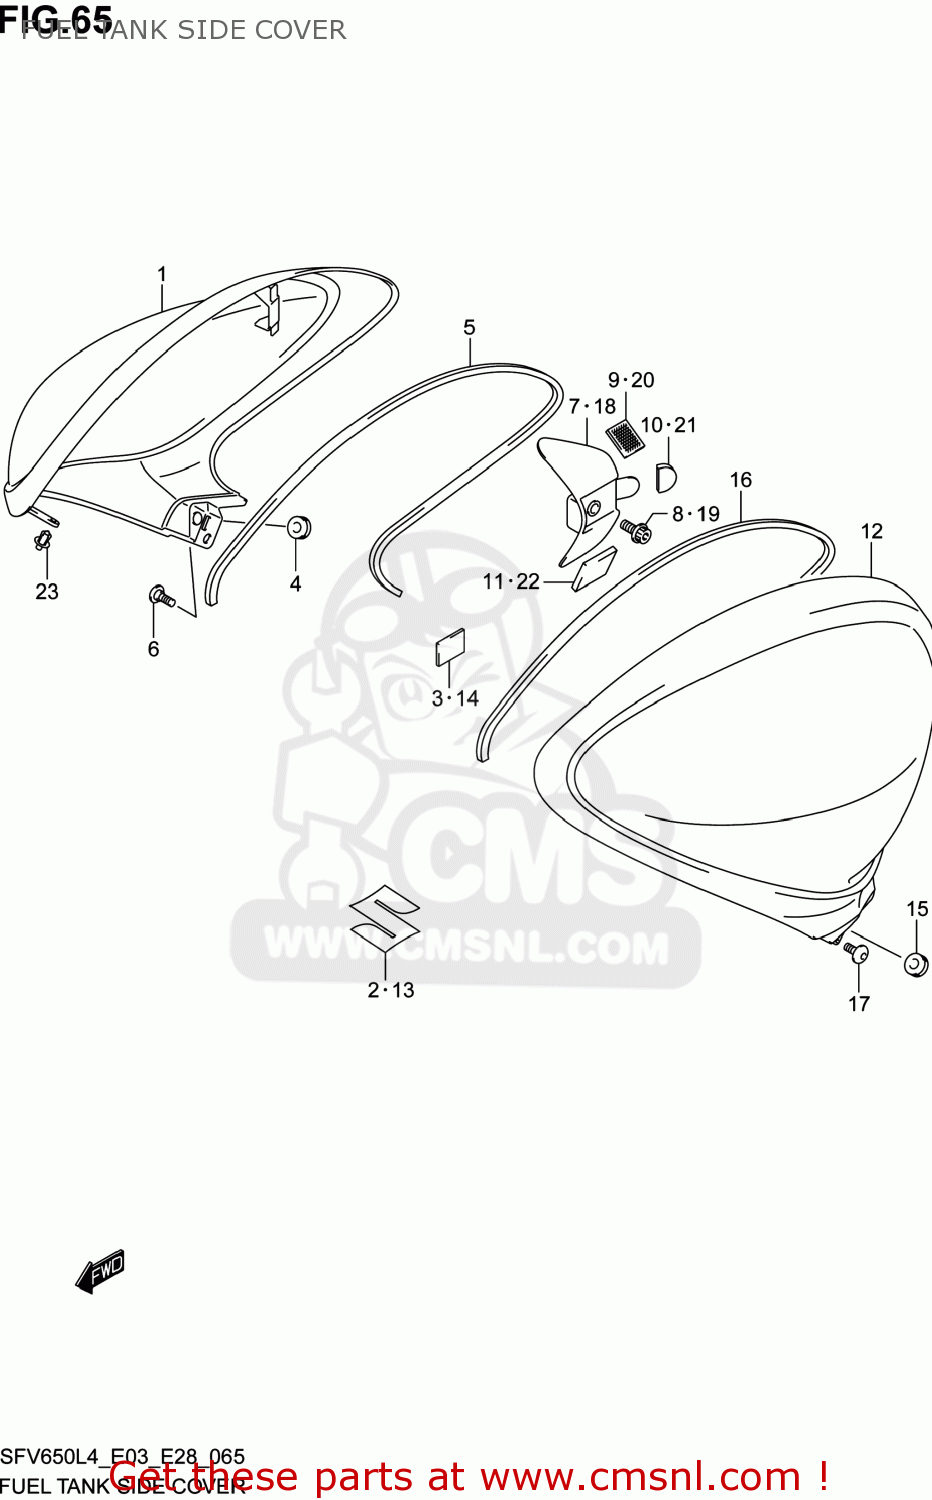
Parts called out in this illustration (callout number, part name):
1	COVER,FUEL TANK SIDE,R
2	EMBLEM, S
3	FASTENER
4	CUSHION
5	CUSHION,FUEL TANK SIDE COVER
6	BOLT(5X13)
7	BRACKET,FUEL TANK COVER,R
8	BOLT
9	FASTENER
10	CUSHION
11	CUSHION,TANK SIDE COVER
12	COVER,FUEL TANK SIDE,L
13	EMBLEM, S
14	FASTENER
15	CUSHION
16	CUSHION,FUEL TANK SIDE COVER
17	BOLT(5X13)
18	BRACKET,FUEL TANK COVER,L
19	BOLT
20	FASTENER
21	CUSHION
22	CUSHION,TANK SIDE COVER
23	CLIP
